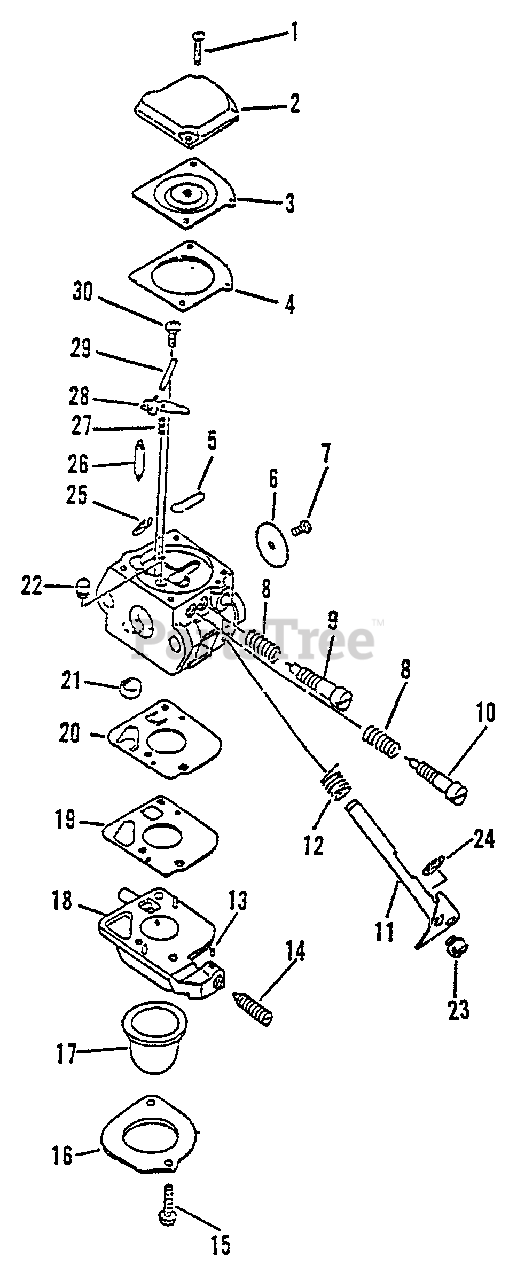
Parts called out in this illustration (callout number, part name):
2	COVER, DIAPHRAGM
3	DIAPHRAGM
4	GASKET, DIAPHRAGM
5	PLUG, WELCH
6	VALVE, THROTTLE
8	SPRING, NEEDLE
9	NEEDLE, LOW SPEED
10	NEEDLE, HIGH SPEED
11	SHAFT, THROTTLE
12	SPRING, THROTTLE RETURN
13	PIECE, FRICTION
14	SCREW, IDLE ADJUST
16	RETAINER
17	BULB, PURGE
18	BODY ASSY, PURGE
19	GASKET, PUMP
20	DIAPHRAGM, PUMP
21	STRAINER
22	NOZZLE, CHECK VALVE
26	VALVE, NEEDLE
27	SPRING, METERING LEVER
28	LEVER, METERING
29	PIN, METERING LEVER
30	SCREW
